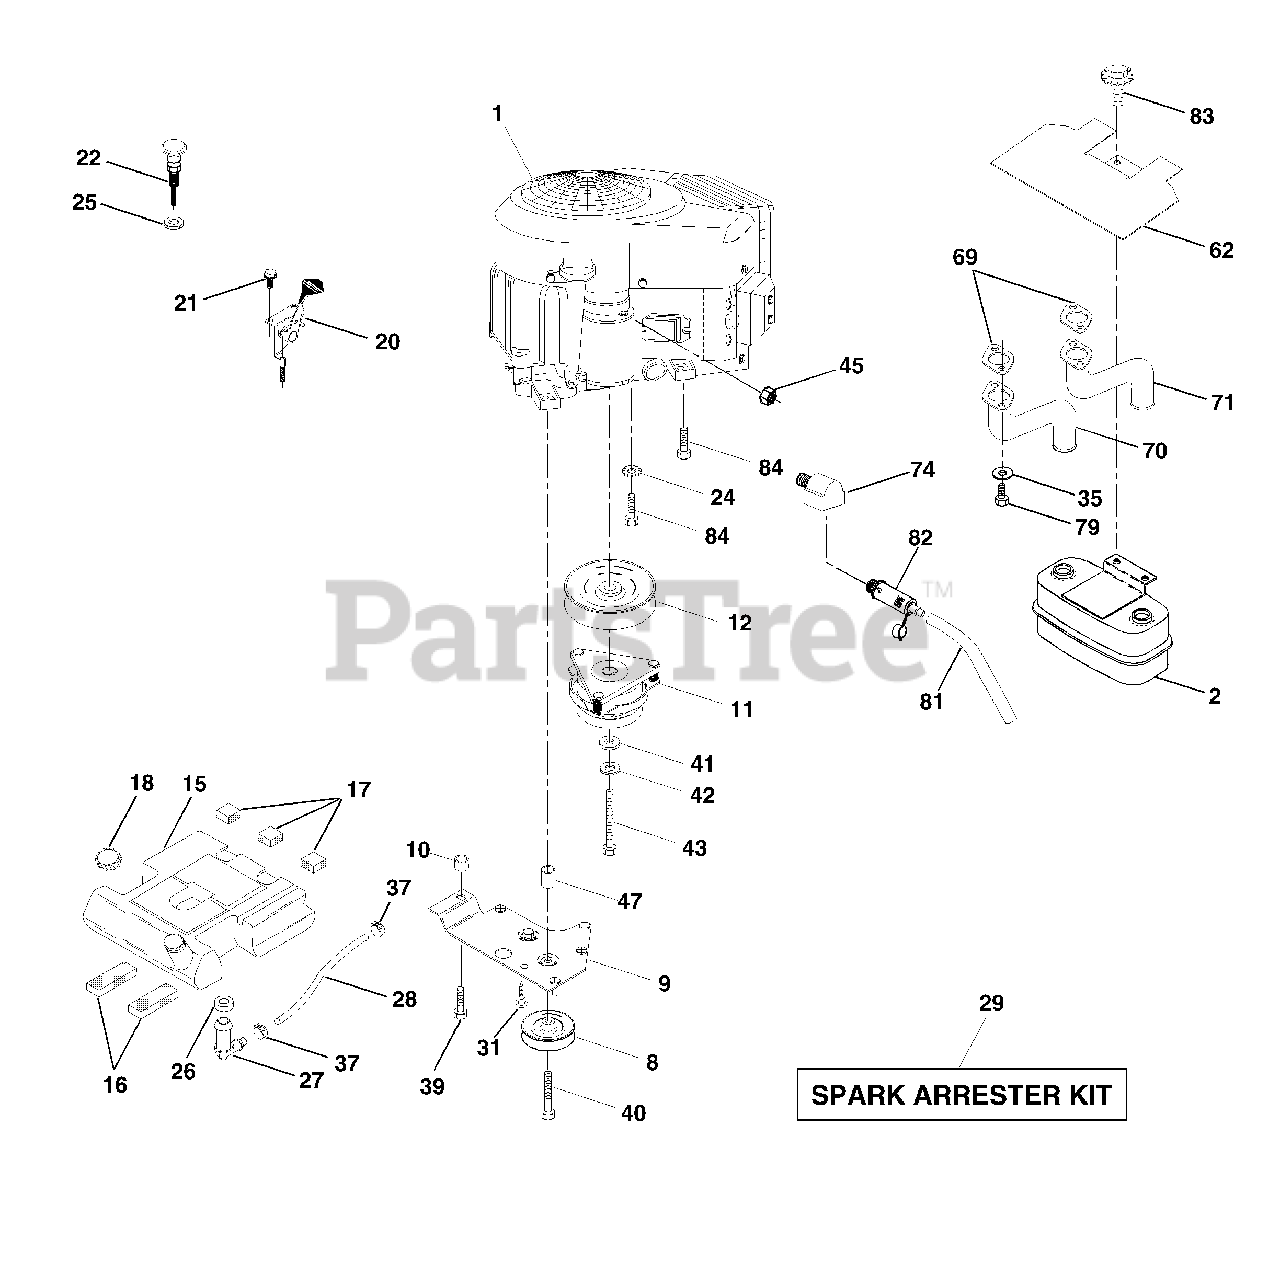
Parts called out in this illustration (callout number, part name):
2	Muffler Side
8	Pulley V-Idler
9	Keeper Asm. Belt Engine VGT
10	Bushing
11	Clutch Electric
12	Pulley Engine VGT Elect Clutch
15	Tank Fuel Rear 3.50
16	Pad Spacer
17	Pad Spacer
18	Top Vented N/LANY
20	Control Throttle
21	Screw Hex Thd Cut 1/4 - 20 X 5/8
22	Control Choke
24	Washer Ext Tooth 3/8
25	Nut Keps 3/8-24 Unf
26	Bushing
27	Stem Tank Fuel
29	Spark Arrester Kit
35	Washer
37	Clamp Hose
39	Screw TT 3/8-16 x 2-1/4 UNC
40	Screw TT 3/8-16 x 4 UNC
41	Washer 1-1/2 OD X 15/32 ID X .250
42	Washer Lock 7/16
43	Bolt Hex 7/16-20 X 4 Gr. 5
45	Nut Keps Hex 1/4-20
47	Spacer
62	Shield Heat Muffler CV-Intek
69	Gasket
70	Tube Exhaust LH
71	Tube Exhaust RH
74	Elbow Street Brass
79	Screw Hex Hd Cap 5/16-18 x 3/4
81	Tube Drain Oil Easy
82	Plug Oil Drain Easy
83	Bolt 5/16-18unc X 1-3/4 W/Sems
84	Screw Thdrol 3/8-16 x 1-1/2
